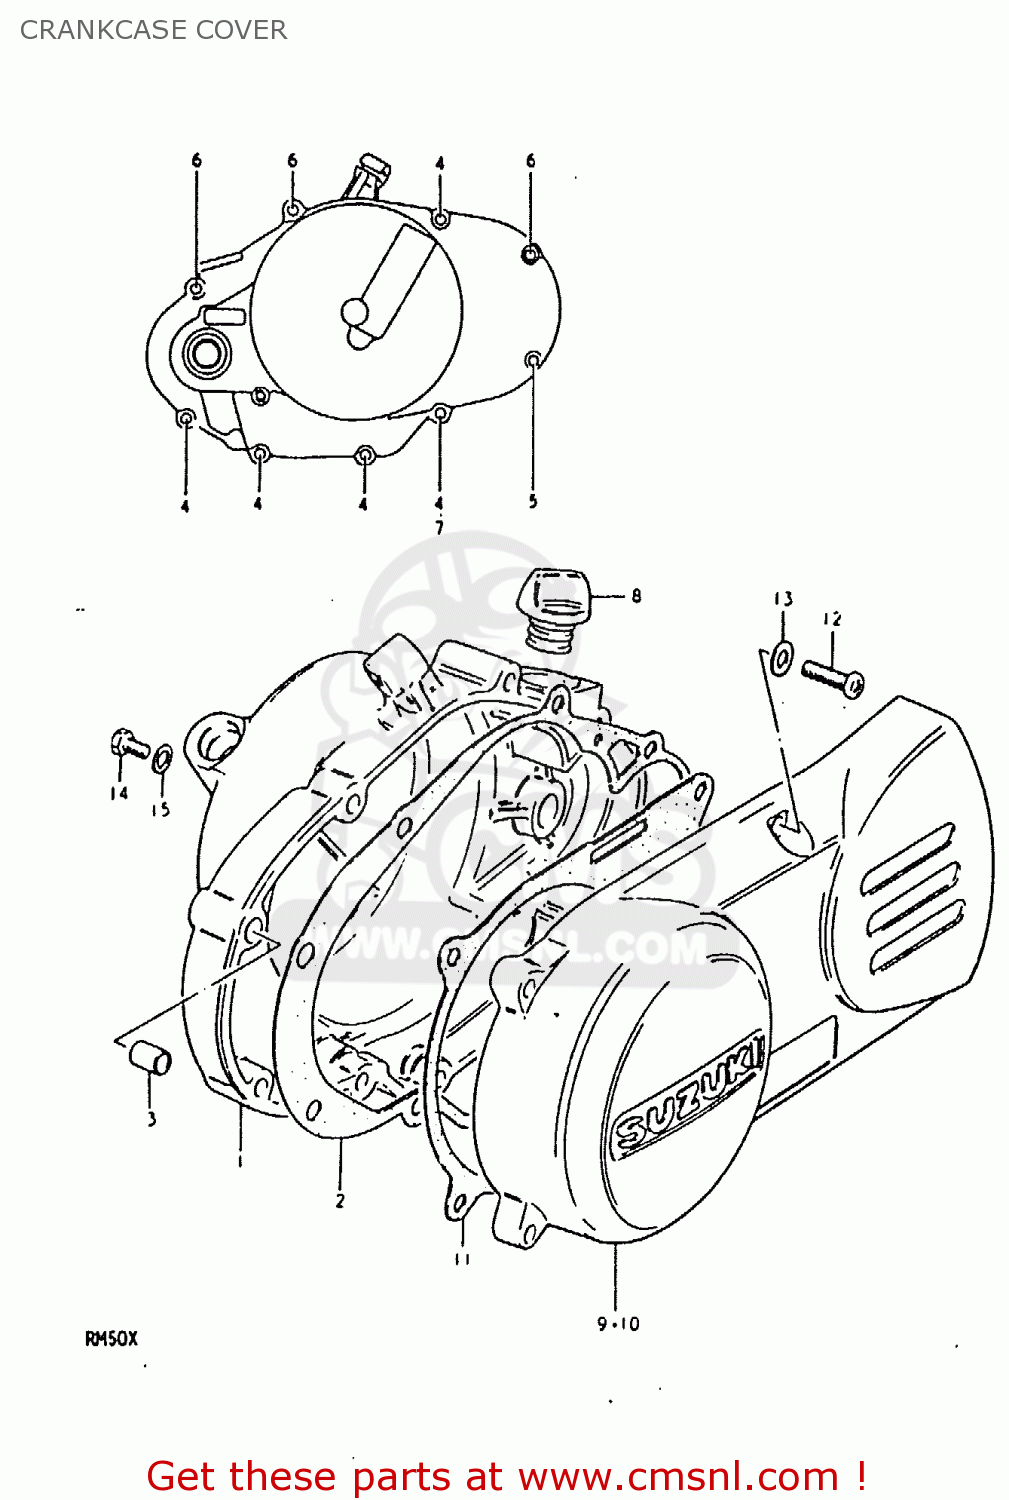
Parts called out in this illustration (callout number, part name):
1	COVER,CLUTCH
2	GASKET,CLUTCH COVER (MCA)
3	PIN
4	SCREW
5	SCREW 6X30
6	SCREW
7	GASKET(6.2X11X1).2 (NAS)
8	PLUG
9	COVER,MAGNETO
10	COVER,MAGNETO
11	GASKET,MAGNETO COVER (NAS)
12	SCREW
13	WASHER
14	SCREW(6X10)
15	GASKET(6.2X11X1) (NAS)
